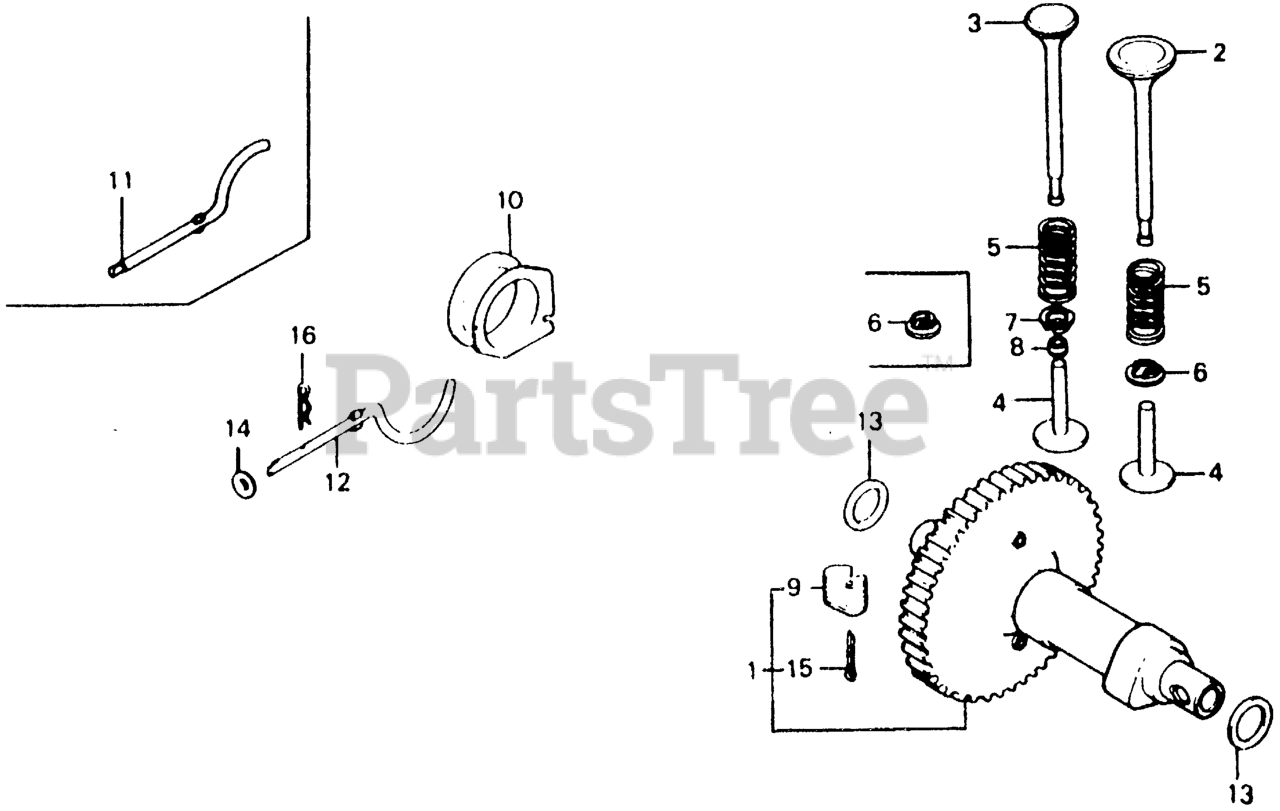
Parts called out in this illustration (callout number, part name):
1	CAMSHAFT ASSY.
2	VALVE, IN.
3	VALVE, EX.
4	LIFTER, VALVE (45.89MM)
4	LIFTER, VALVE (46.04MM)
4	LIFTER, VALVE (46.19MM)
4	LIFTER, VALVE (46.34MM)
5	SPRING, VALVE
6	RETAINER, VALVE SPRING
7	RETAINER, VALVE SPRING
8	ROTATOR, EX. VALVE
9	WEIGHT, GOVERNOR
10	SLIDER, GOVERNOR
12	SHAFT, GOVERNOR
13	WASHER, THRUST (18MM)
14	WASHER, PLAIN (6MM)
15	PIN, SPLIT (3.0X25)
15	PIN, COTTER (3.0X45)
16	PIN, LOCK (10MM)
